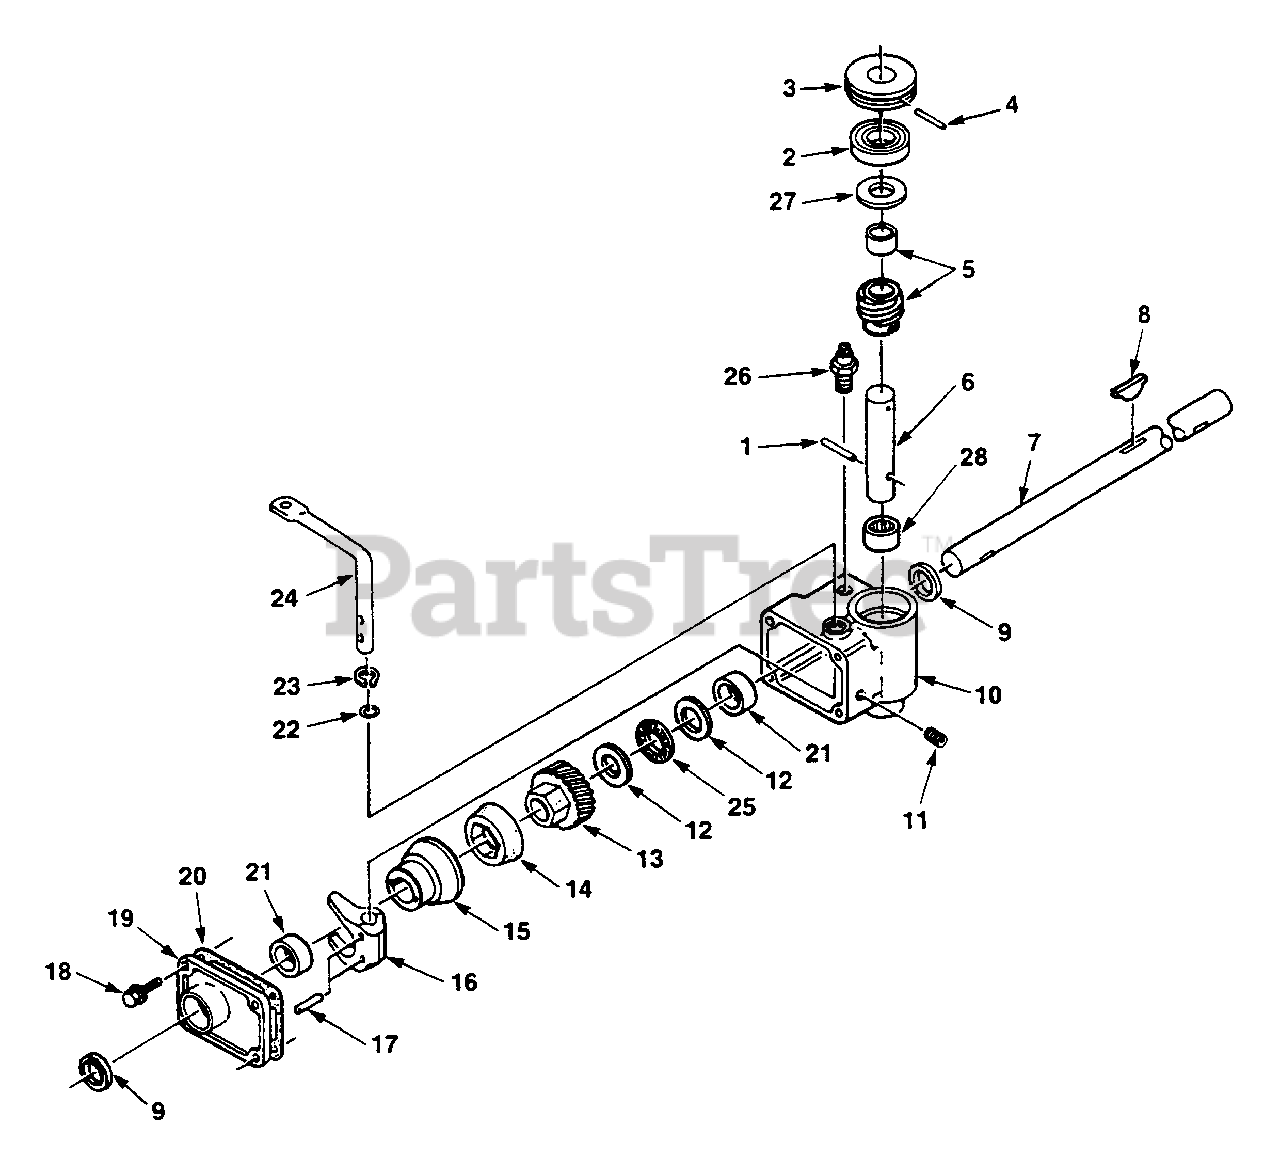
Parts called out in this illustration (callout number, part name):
3	PULLEY
5	WORM & SPACER
6	SHAFT- Worm
7	SHAFT- Drive
10	GEAR REDUCER HOUSING ASSY.
12	RACE- Bearing
13	GEAR- Helical
14	CONE- Friction
15	DRUM- Clutch
16	FORK- Shift
18	SCREW- Sems thd. forming 1/4-20 x 7/8
19	COVER- Gearbox
20	GASKET
21	BUSHING- Sleeve
24	LEVER- Shift
25	BEARING- Thrust
28	BEARING- Needle
